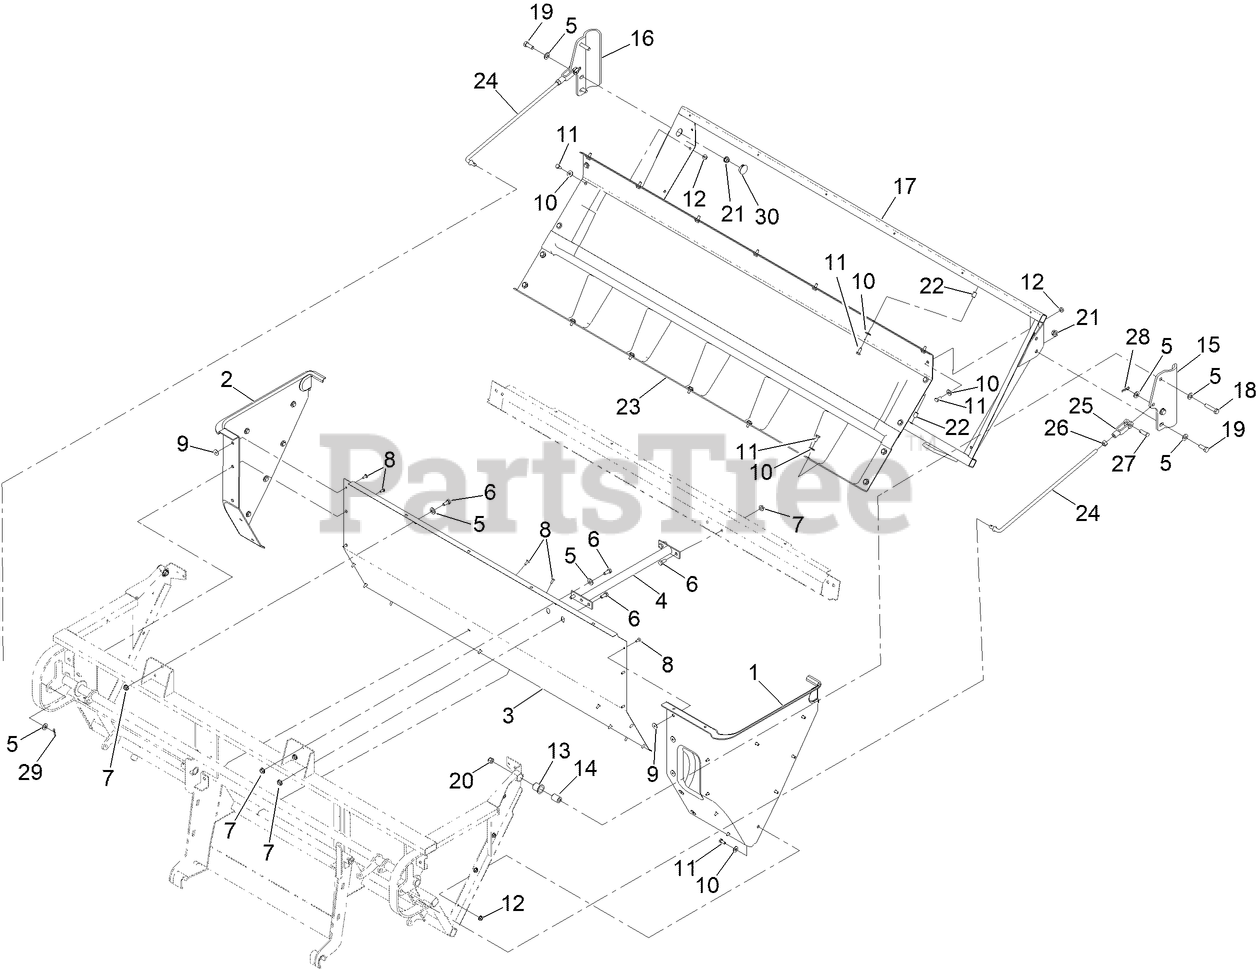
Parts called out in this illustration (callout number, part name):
1	PANEL-BAGGER, LH
2	PANEL-BAGGER, RH
3	SHEET-WALL
5	WASHER-FLAT
6	SCREW-HH
7	NUT-HF
8	RIVET-BLIND
9	WASHER-FLAT
10	WASHER-FLAT
11	SCREW-HH
12	NUT-HF
13	BUSHING
14	PIN-PIVOT, HINGE
15	ARM-HINGE, LH
16	ARM-HINGE, RH
17	FRAME-DOOR
18	SCREW-HH
19	SCREW-HH
20	NUT-LOCK, NI
21	NUT-HHF, WHIZ
22	NUT-CLINCH
23	BAG AND BOTTOM PANEL ASM
24	LINK-HINGE
25	YOKE-LINKAGE, BRAKE
26	NUT-HEX
27	PIN-CLEVIS
28	PIN-COTTER
29	PIN-COTTER
30	PLUG-DOME
